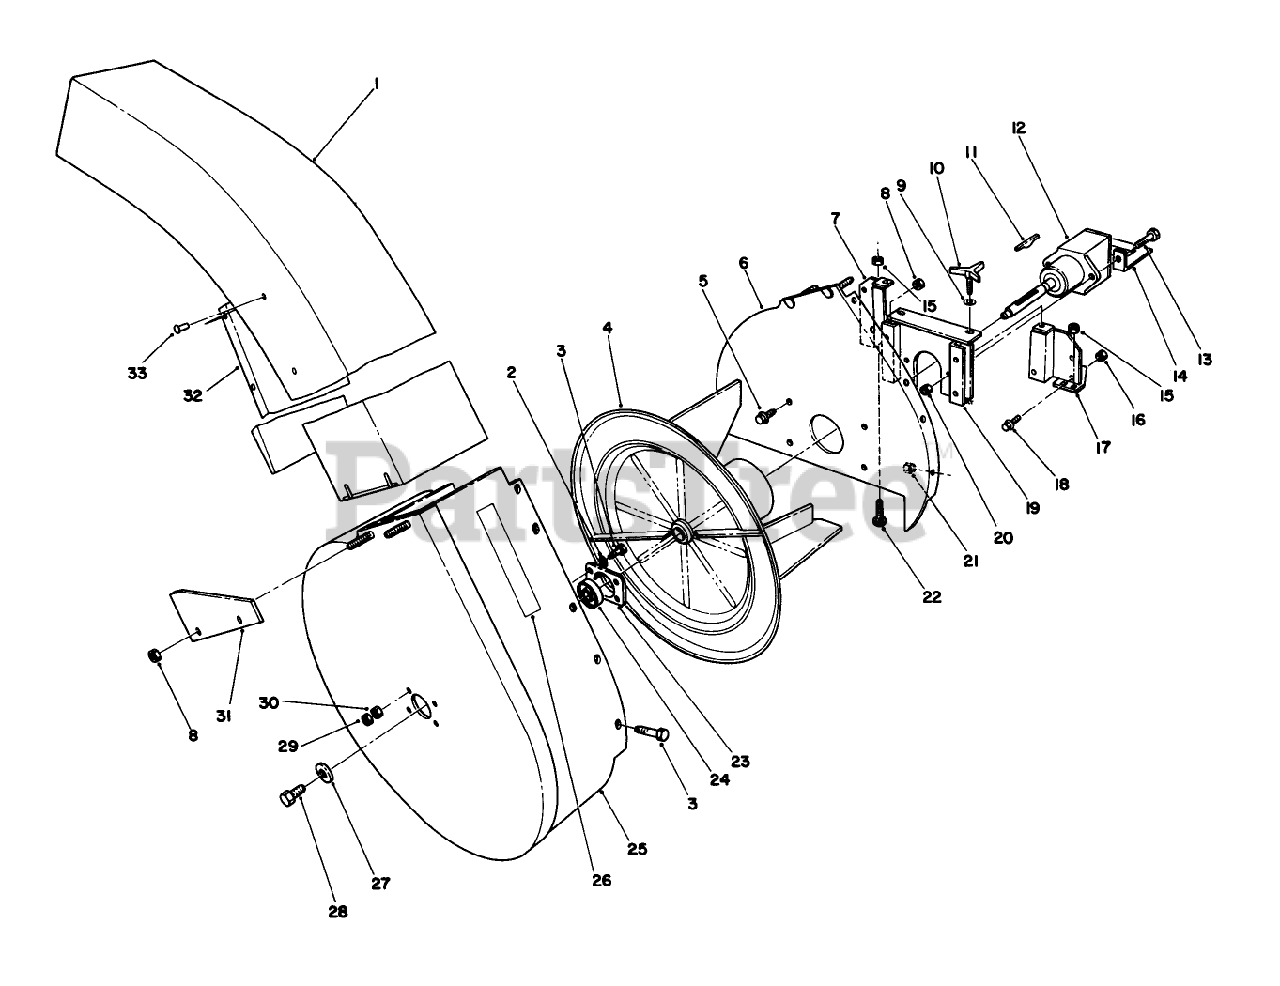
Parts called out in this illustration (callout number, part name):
1	CHUTE ASM
2	WASHER-LOCK
3	SCREW-HH
5	SCREW-HHF
7	LH BLWR MT BRKT WA *B
8	NUT-LOCK, NI
9	WASHER-FLAT
13	SCREW-HH
15	NUT-KEPS
16	NUT-JAM
17	RH BLWR MT BRKT WA
18	SCREW-HHF
20	NUT-LOCK, NI
21	NUT-LOCK, NI
22	SCREW-CARR
23	CUP-BEARING
24	BEARING-BALL
27	SPACER
29	NUT-JAM
30	NUT-HEX
